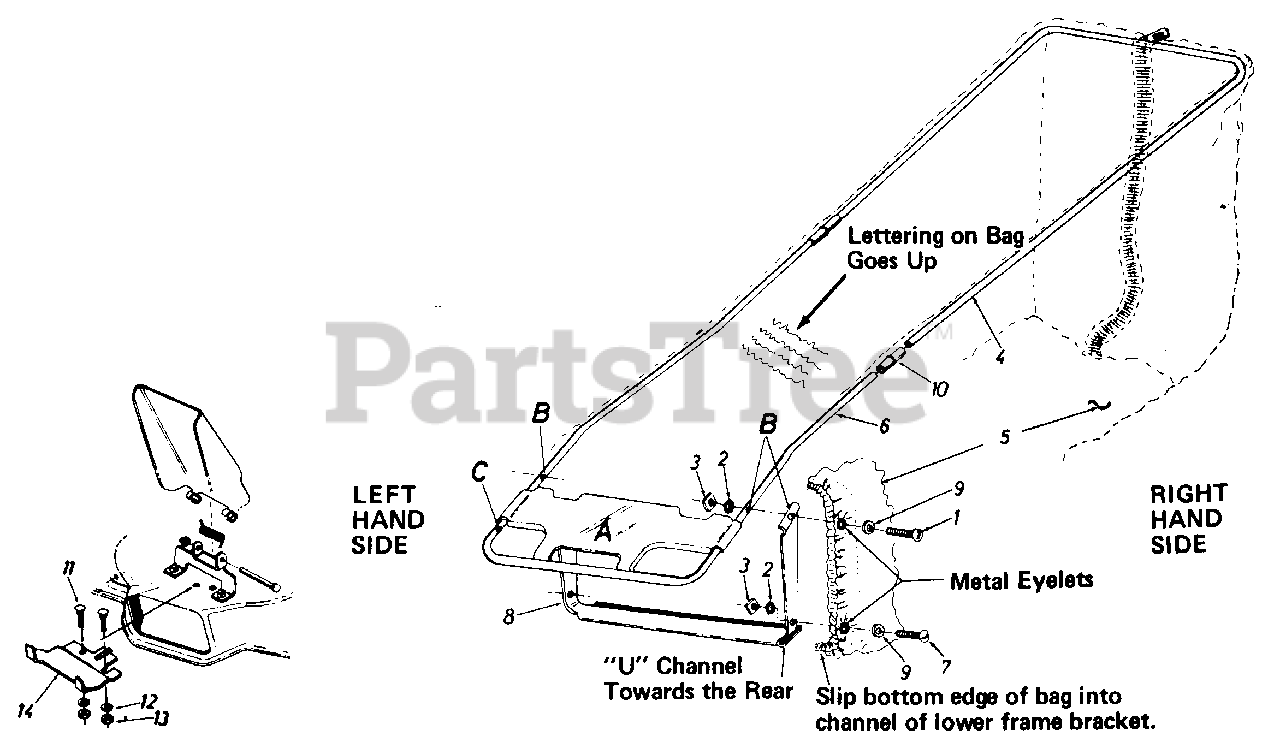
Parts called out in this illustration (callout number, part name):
1	SCREW-TRUSS MACH #10-24 X 1.00
2	WASHER-EXTERN L #10
3	NUT-SQ-10-24
4	FRAME-UPPER
5	BAG-GRASS-MTD-STD
6	FRAME-LOWER
7	SCREW-TRUSS MACH #10-24 X .62
8	BRACKET-FRAME-LWR
9	WASHER-FL-.203 ID X .41 OD X .040
10	CONNECTOR
11	BOLT-CARRIAGE 1/4-20 X .50
12	LOCK WASHER 1/4 DIA
13	NUT-HEX 1/4-20
14	PLATE-ADAPTER
